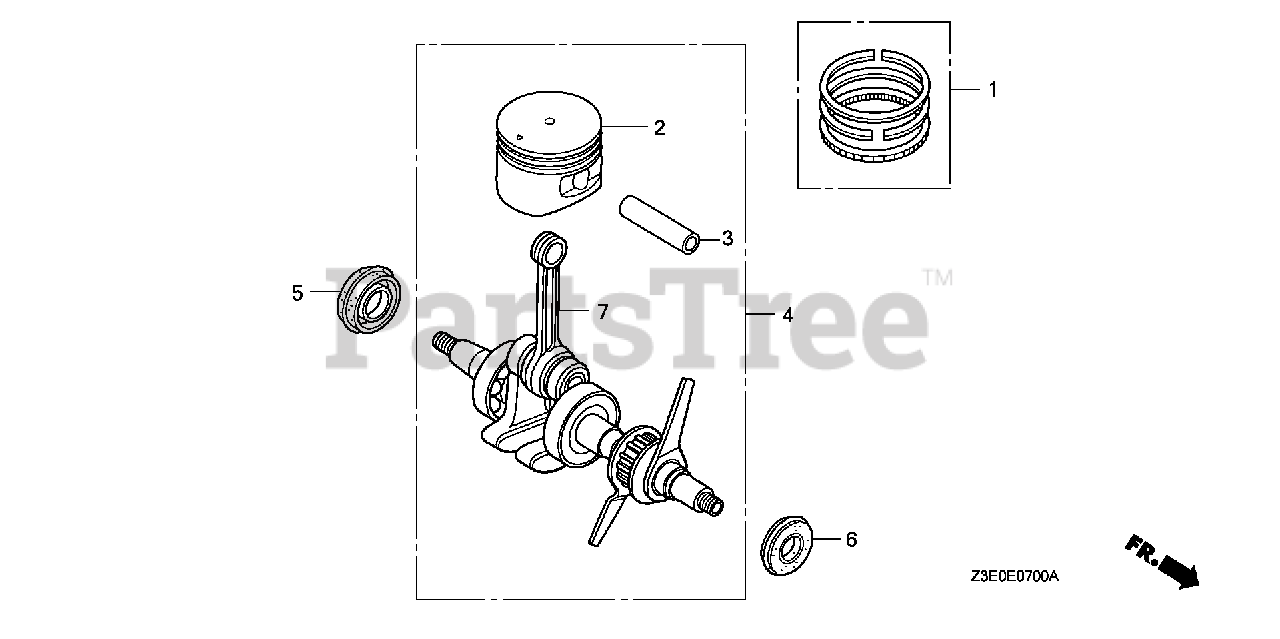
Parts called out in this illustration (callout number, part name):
1	RING SET, PISTON
1	RING SET, PISTON (TPR)
2	PISTON (STD)
3	PIN, PISTON
4	CRANKSHAFT
5	OIL SEAL (12X24X5)
6	OIL SEAL (10X20X5)
7	CRANKSHAFT
